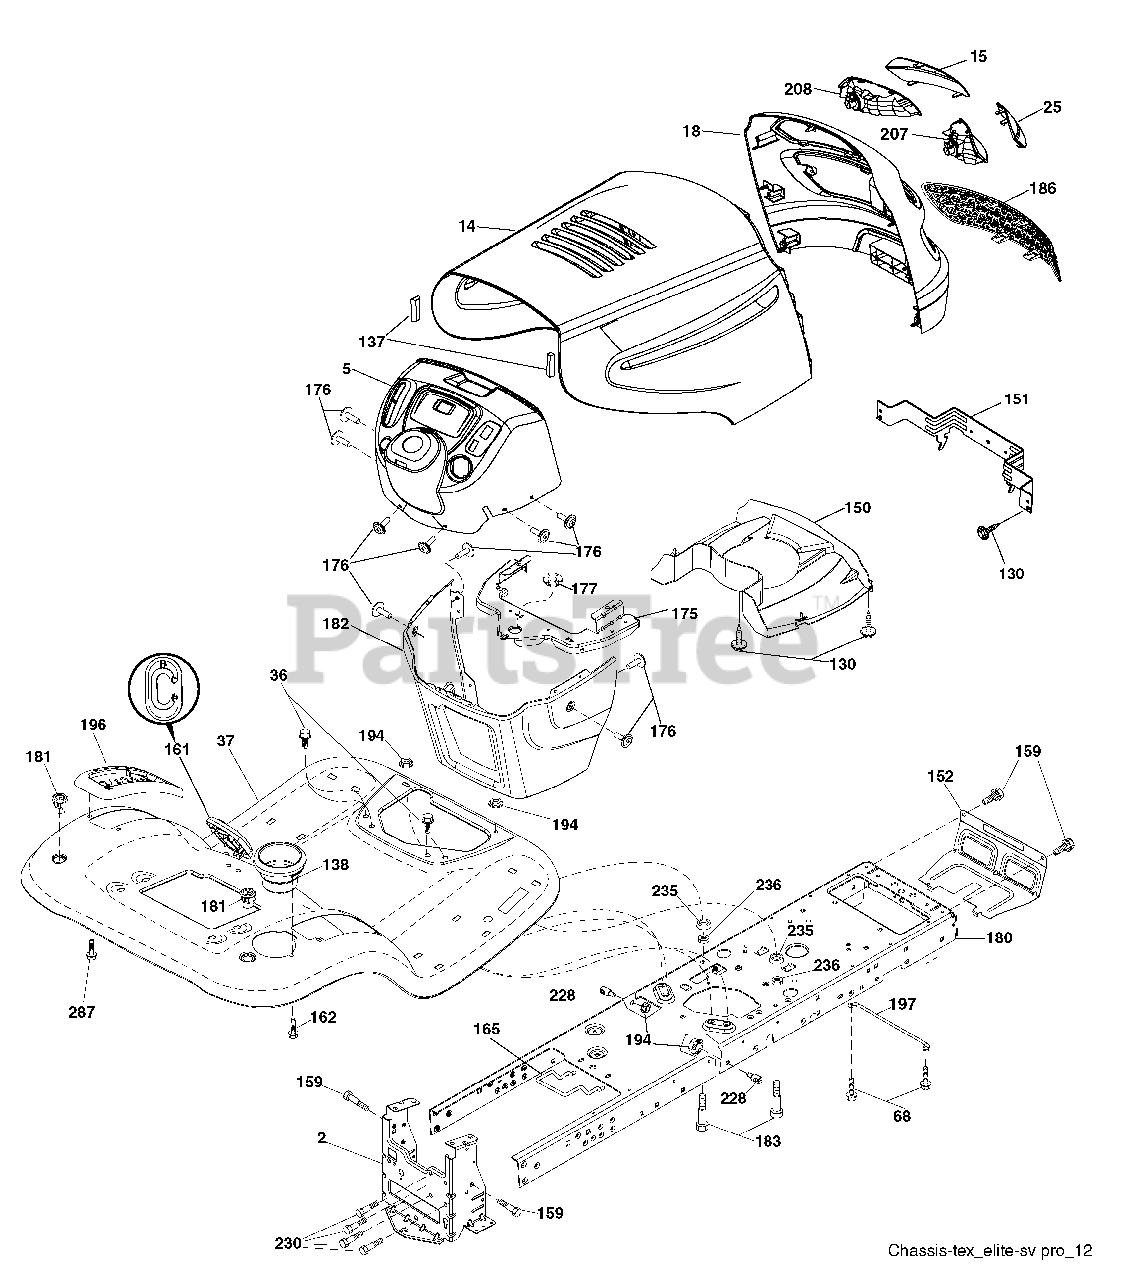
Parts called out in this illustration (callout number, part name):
2	Drawbar
5	Dash
14	Hood
15	Lens Grille LH
18	Grille
25	Lens Grille RH
36	Screw 5/16-18 x 3/4
37	Fender
68	Screw THDROL 5/16-18 x 1/2
130	Screw #10 x 0.750 BOS Thread
137	Bumper Hood
138	Cupholder
150	Duct Heat Hood
151	Bracket Pivot
152	Shield Browning/Debris
159	Screw Hexwsh Thdrol 3/8-16 x 3/4
161	Window Fuel
162	Screw Hex Wsh Hi-Lo 1/4 x 1/2 unc
165	Bracket Support Tank
175	Crossmember
176	Screw 10-24 x 5/8 Wshd Qdrx
177	Bushing Steering
181	Bushing Mtg. Fender Crgo.
182	Dash Lower
183	Bolt Fin Hex 5/16-18 x 1-1/4
194	Nut Lock Hex Flange 5/16-18
196	Console Asm. Deck Lift
197	Rod Pivot Chassis
207	Bezel RH
208	Bezel LH
228	Stud Fastener
230	Bolt Shoulder 5/16-18
235	Spacer Fender
236	Nut Center lock 5/16-18 unc
287	Screw Hex Washead 1/4-20 x 3/8
